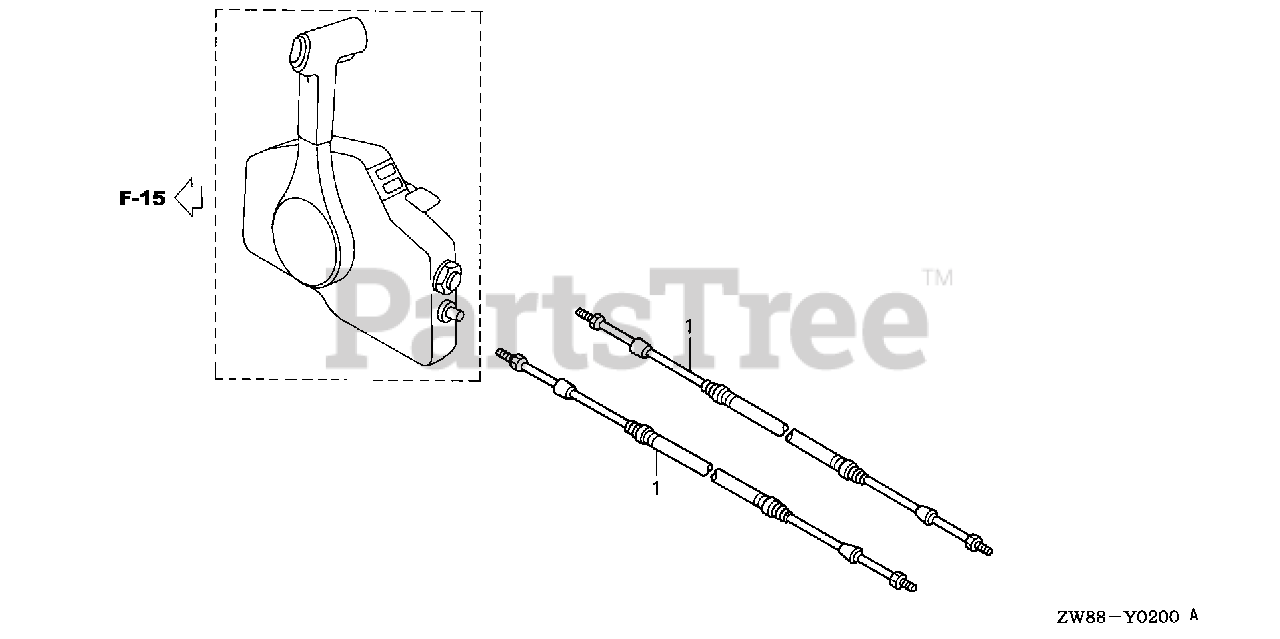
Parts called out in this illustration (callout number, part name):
1	CABLE, REMOTE CONTROL (10') (LOW FRICTION)
1	CABLE ASSY., PUSH-PULL (33C-5FT)
1	CABLE, REMOTE CONTROL (11') (LOW FRICTION)
1	CABLE ASSY., PUSH-PULL (33C-6FT)
1	CABLE, REMOTE CONTROL (12') (LOW FRICTION)
1	CABLE ASSY., PUSH-PULL (33C-7FT)
1	CABLE, REMOTE CONTROL (13') (LOW FRICTION)
1	CABLE ASSY., PUSH-PULL (33C-8FT)
1	CABLE, REMOTE CONTROL (14') (LOW FRICTION)
1	CABLE ASSY., PUSH-PULL (33C-9FT)
1	CABLE, REMOTE CONTROL (15') (LOW FRICTION)
1	CABLE ASSY., PUSH-PULL (33C-10FT)
1	CABLE, REMOTE CONTROL (16') (LOW FRICTION) (NOT AVAILABLE)
1	CABLE ASSY., PUSH-PULL (33C-11FT)
1	CABLE, REMOTE CONTROL (17') (LOW FRICTION)
1	CABLE ASSY., PUSH-PULL (33C-12FT)
1	CABLE, REMOTE CONTROL (18') (LOW FRICTION) (NOT AVAILABLE)
1	CABLE ASSY., PUSH-PULL (33C-13FT)
1	CABLE, REMOTE CONTROL (19') (LOW FRICTION)
1	CABLE ASSY., PUSH-PULL (33C-14FT)
1	CABLE, REMOTE CONTROL (20') (LOW FRICTION) (NOT AVAILABLE)
1	CABLE ASSY., PUSH-PULL (33C-15FT)
1	CABLE, REMOTE CONTROL (21') (LOW FRICTION)
1	CABLE ASSY., PUSH-PULL (33C-16FT)
1	CABLE, REMOTE CONTROL (22') (LOW FRICTION) (NOT AVAILABLE)
1	CABLE ASSY., PUSH-PULL (33C-17FT)
1	CABLE, REMOTE CONTROL (23') (LOW FRICTION)
1	CABLE ASSY., PUSH-PULL (33C-18FT)
1	CABLE, REMOTE CONTROL (24') (LOW FRICTION) (NOT AVAILABLE)
1	CABLE ASSY., PUSH-PULL (33C-19FT)
1	CABLE, REMOTE CONTROL (25') (LOW FRICTION)
1	CABLE ASSY., PUSH-PULL (33C-20FT)
1	CABLE, REMOTE CONTROL (26') (LOW FRICTION)
1	CABLE ASSY., PUSH-PULL (33C-21FT)
1	CABLE, REMOTE CONTROL (27') (LOW FRICTION)
1	CABLE ASSY., PUSH-PULL (33C-22FT)
1	CABLE, REMOTE CONTROL (28') (LOW FRICTION) (NOT AVAILABLE)
1	CABLE ASSY., PUSH-PULL (33C-23FT)
1	CABLE, REMOTE CONTROL (29') (LOW FRICTION)
1	CABLE ASSY., PUSH-PULL (33C-24FT)
1	CABLE, REMOTE CONTROL (30') (LOW FRICTION) (NOT AVAILABLE)
1	CABLE ASSY., PUSH-PULL (33C-25FT)
1	CABLE, REMOTE CONTROL (31') (LOW FRICTION)
1	CABLE ASSY., PUSH-PULL (33C-26FT)
1	CABLE, REMOTE CONTROL (32') (LOW FRICTION) (NOT AVAILABLE)
1	CABLE ASSY., PUSH-PULL (33C-27FT)
1	CABLE, REMOTE CONTROL (33') (LOW FRICTION)
1	CABLE ASSY., PUSH-PULL (33C-28FT)
1	CABLE, REMOTE CONTROL (34') (LOW FRICTION) (NOT AVAILABLE)
1	CABLE ASSY., PUSH-PULL (33C-29FT)
1	CABLE, REMOTE CONTROL (35') (LOW FRICTION)
1	CABLE ASSY., PUSH-PULL (33C-30FT)
1	CABLE ASSY., PUSH-PULL (33C-31FT)
1	CABLE ASSY., PUSH-PULL (33C-32FT)
